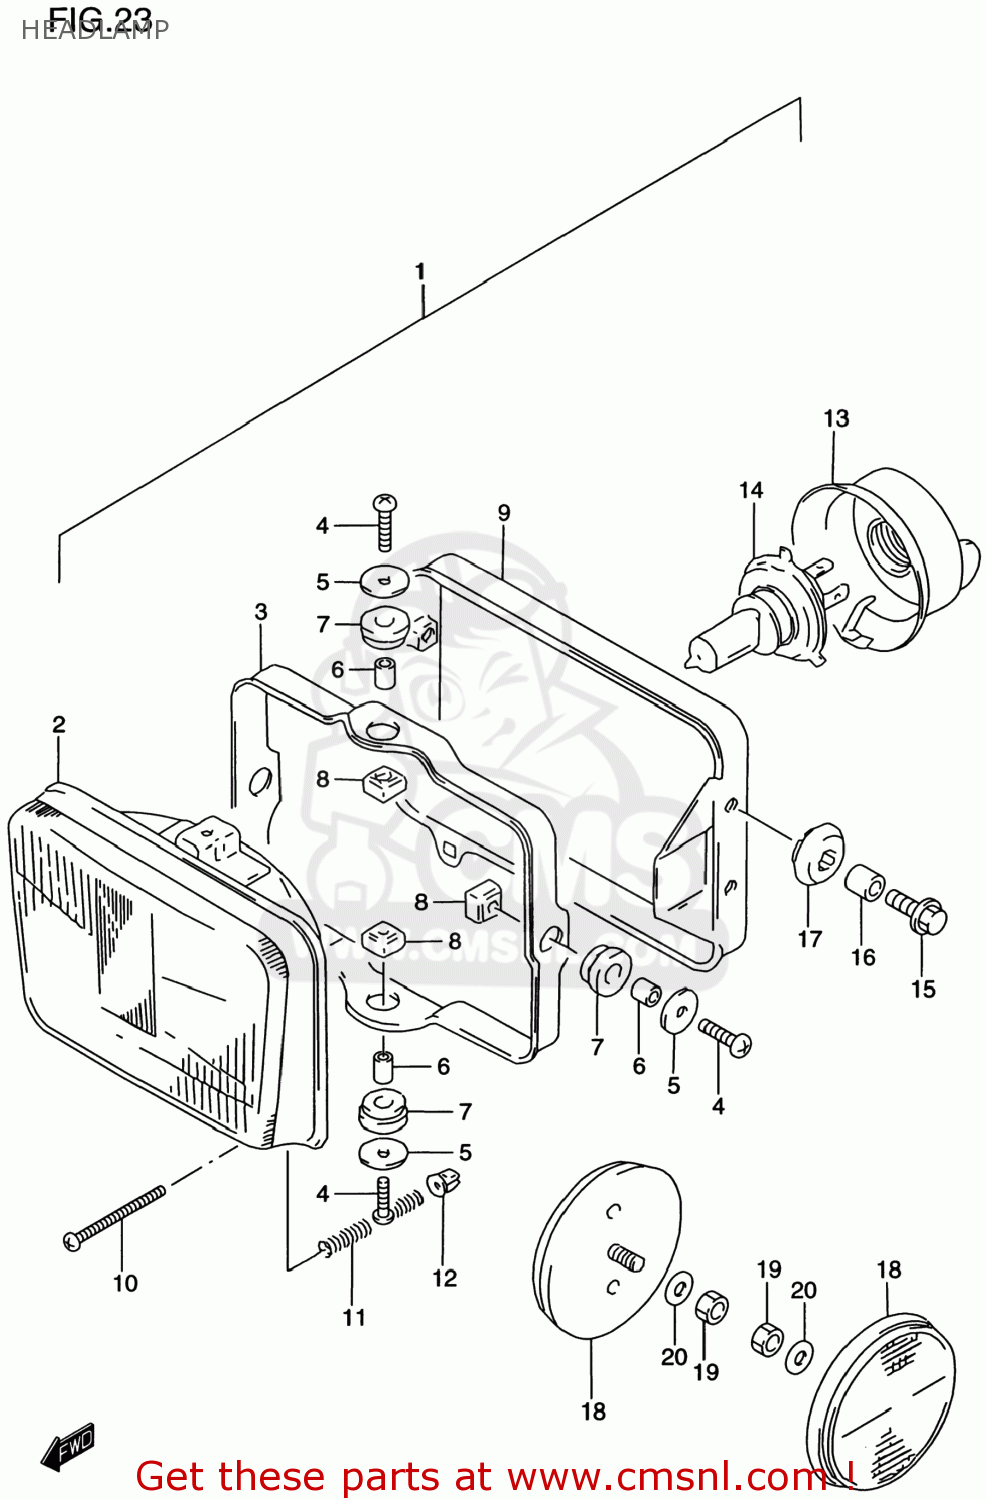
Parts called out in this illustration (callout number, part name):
1	HEADLAMP ASSEMBLY
2	UNIT ASSY
3	RING,MOUNTING
4	SCREW
5	WASHER(5.5X18X1)
6	SPACER
7	CUSHION
8	NUT
9	HOUSING
10	SCREW(4X45)
11	SPRING,ADJUSTING
12	NUT,ADJUSTING
13	COVER,SOCKET
14	BULB(12V60/55W,H4)
15	BOLT(6X20)
16	SPACER(6.5X10X10)
17	CUSHION
18	REFLECTOR,REFLEX
19	NUT
20	LOCK,WASHER
